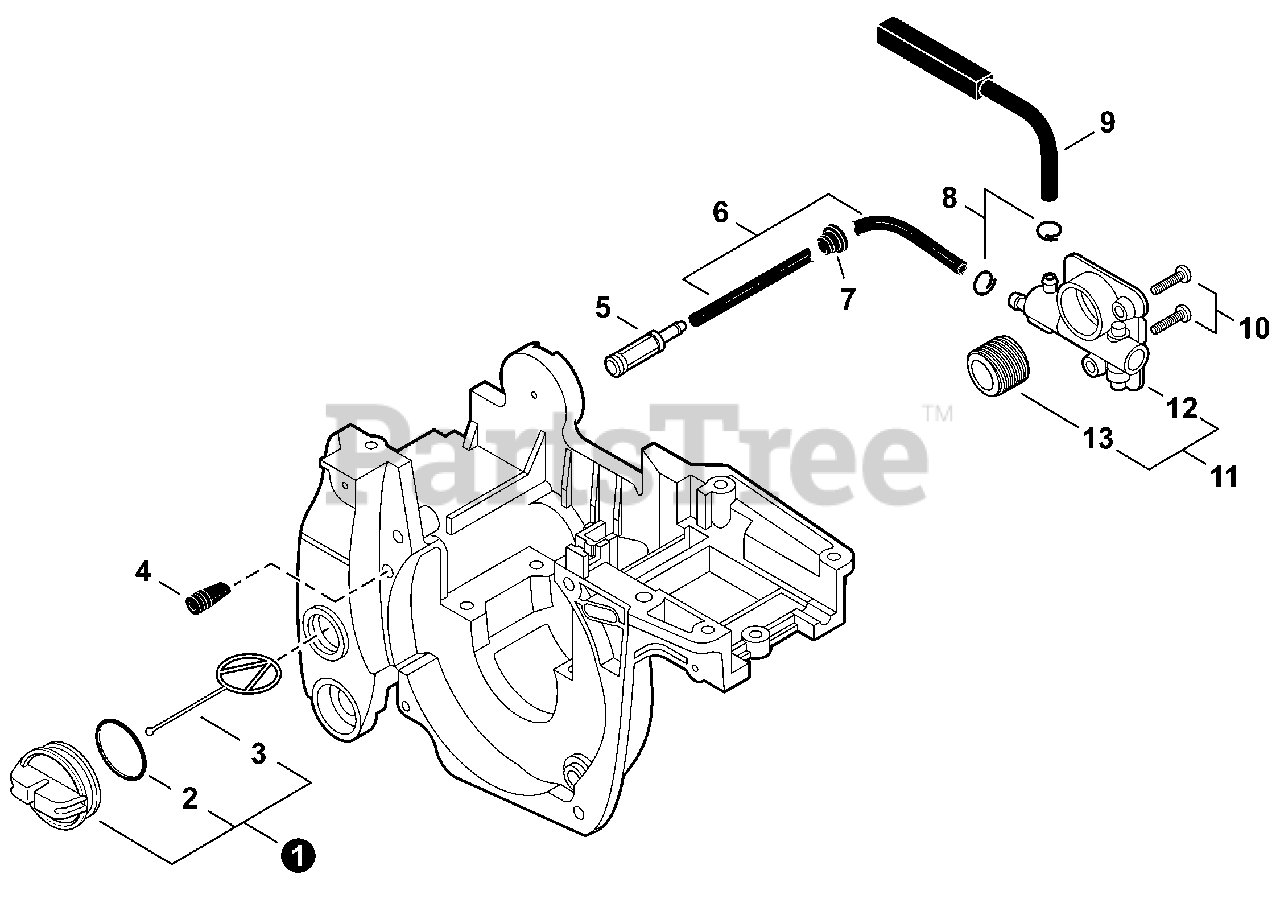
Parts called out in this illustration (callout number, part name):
1	CAP ASSY
2	O-RING 25
3	CONNECTOR, CAP L= 60 MM
4	VENT ASSY
5	FILTER, OIL
6	PIPE, OIL
8	CLIP Ø6.5 MM
9	PIPE, OIL OUTLET
10	SCREW 4×12
11	AUTO-OILER KIT
12	AUTO-OILER ASSY
13	GEAR, WORM
